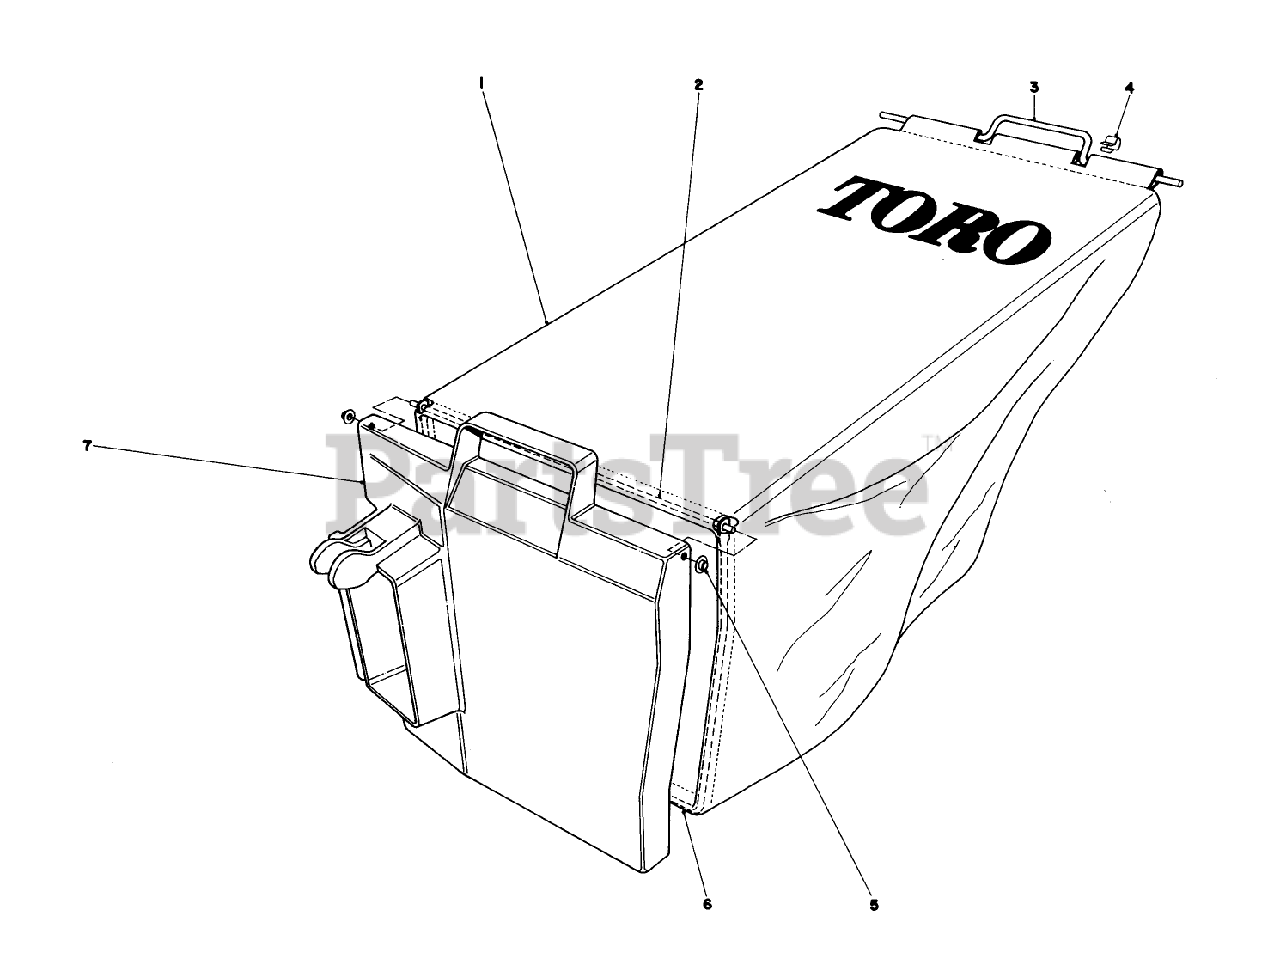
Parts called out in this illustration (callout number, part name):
1	18 BAGGER BAG 33-4552
2	HINGE
3	Handle Bag
5	NUT-PUSH
6	Frame Bag
7	Door-Bag
